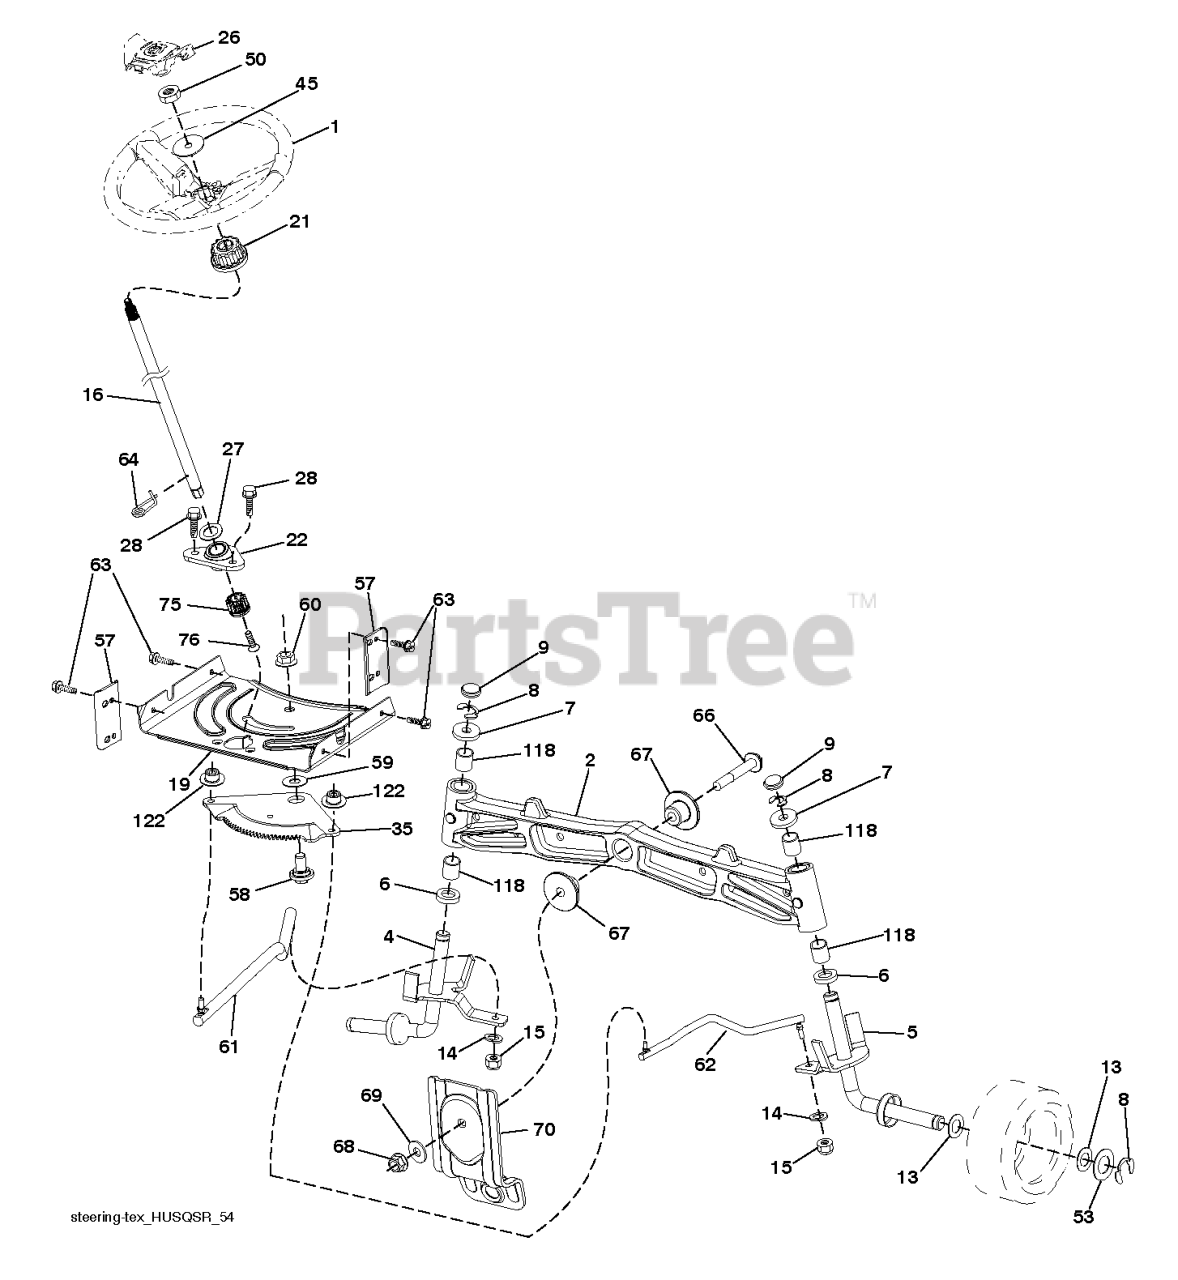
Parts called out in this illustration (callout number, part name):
1	WHEEL.STEER.HUSQ.SR.498.OVMLD
2	AXLE.SVC.ASM CAST IRON.TEX
4	SPINDLE.WELDED.LH.15"TEX
5	SPINDLE.WELDED.RH.15"T
6	THRUST WASHER
9	CAP.SPINDLE.BLACK
14	SLW 3/8 STD
15	NUT CROWNLOCK 3/8-24
16	SHAFT.STEER.2HIGH.SPLND.PLATED
19	PLATE.STEER.DDL.NLT/NG
21	ADAPTER.WHEEL.STEER.SPLND.ALUM
22	BEARING.SHAFT.STEER.LOWER.625
26	INSERT.CAP.WHL.STRG.HUSQ.PREM
28	SCREW, 3/8-16X3/4
35	GEAR.SECTOR.PLATE.DDL.
45	WASHER.3/8ID.2-3/8OD.12GA.PLTD
50	NUT LOCK FLG 3/8-16 UNC
53	WASHER.HARDENED
57	BRACKET.UPSTOP.TEX
58	BOLT.SHOULDER.SECTOR.P
59	WASHER.THURST.SECTOR.S
60	NUT FLANGE LOCK 5/8-11
61	LINK.ASM.DRAG.ADJUST.LH.PLATED
62	LINK.ASM.DRAG.ADJUST.RH.PLATED
63	SCREW
64	RETAINER.CLIP.SPRING.S
66	BOLT HEX FGHD 7/16-14 X 3 SERR
67	BUSHING.PM.FRONT AXLE
68	NUT.LOCK.FLANGE.7/16
69	WASHER.1.5X.505X.118
70	BRACKET.FRT.DECK.SUSP.RR.MT431
75	PINION.ZINC PLATED
76	SCREW HEAD SOCKET LRVB
118	BUSHING, AXLE CAST
122	CAP.GEAR.SECTOR.TEX
